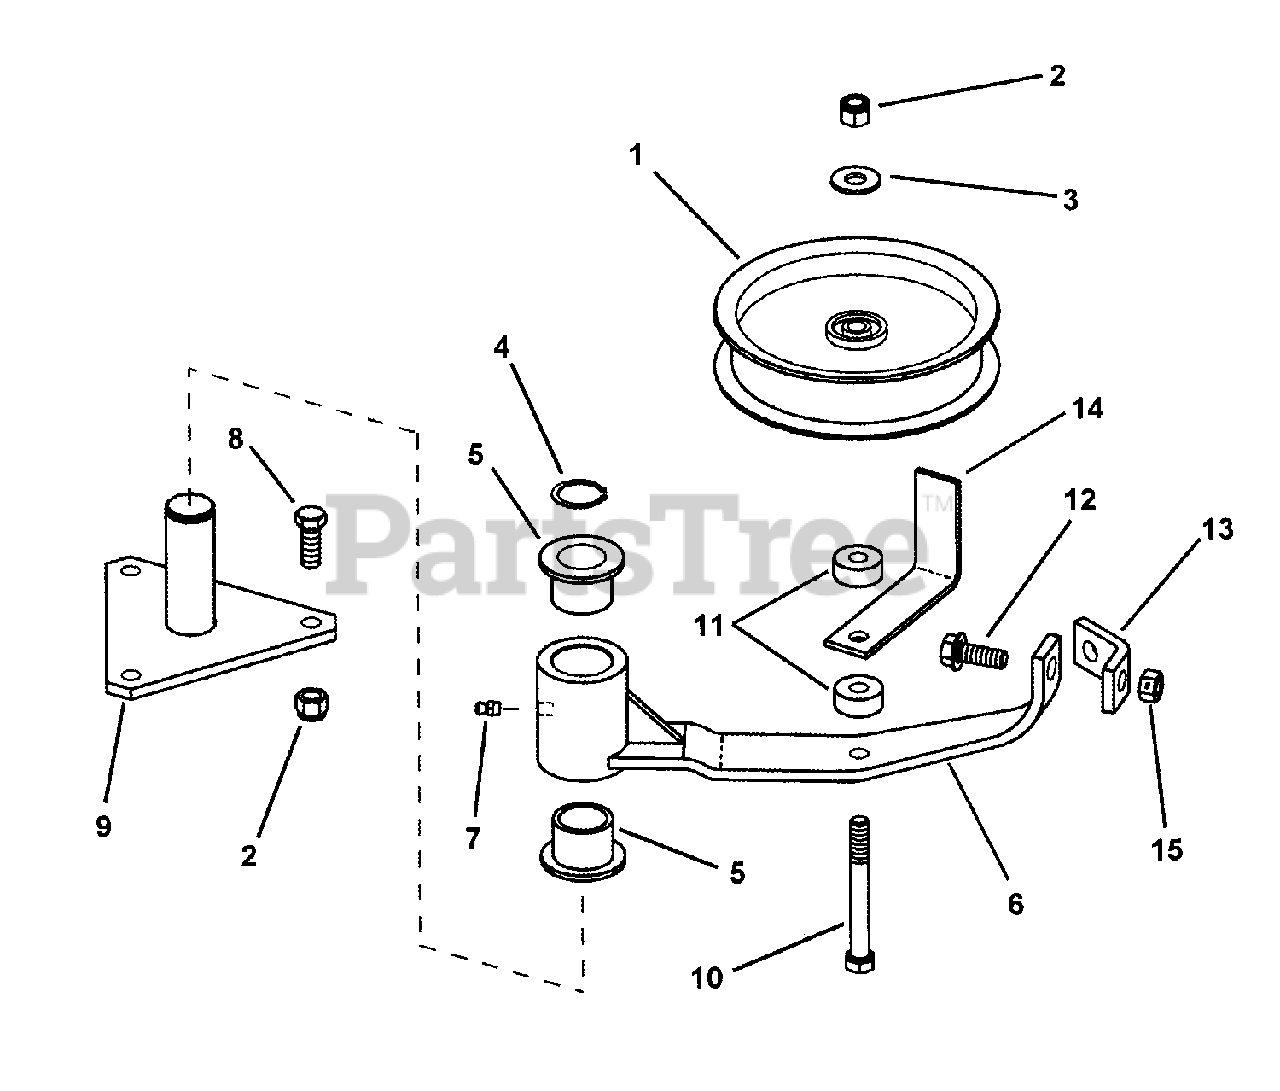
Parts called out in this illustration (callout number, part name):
1	PULLEY, Idler (5.00 O. D.)
2	NUT, 3/8-16 HEX NYLON LOCK
3	WASHER, .44 x 1.0 x .08 Flat
4	RING, 1" External Retaining
5	BUSHING
6	IDLER ARM, 36" (Weldment)
7	GREASE FITTING, 1/4-28 Straight
8	BOLT, 3/8-16 X 1" GD5 CZ
9	PIVOT, Idler Arm (Weldment)
10	BOLT, 3/8-16 x 3-1/4" Hex Head, GR 5
11	SPACER, .380 I.D. x 1" O.D. x .410 Thick
12	BOLT, 3/8-16 x 1" Hex Flange Lock, GR 5
13	BRACKET, Idler (Pro 36)
14	RETAINER, Belt - Idler
15	NUT, 3/8-16 Hex Center Lock, GR 5 or B
